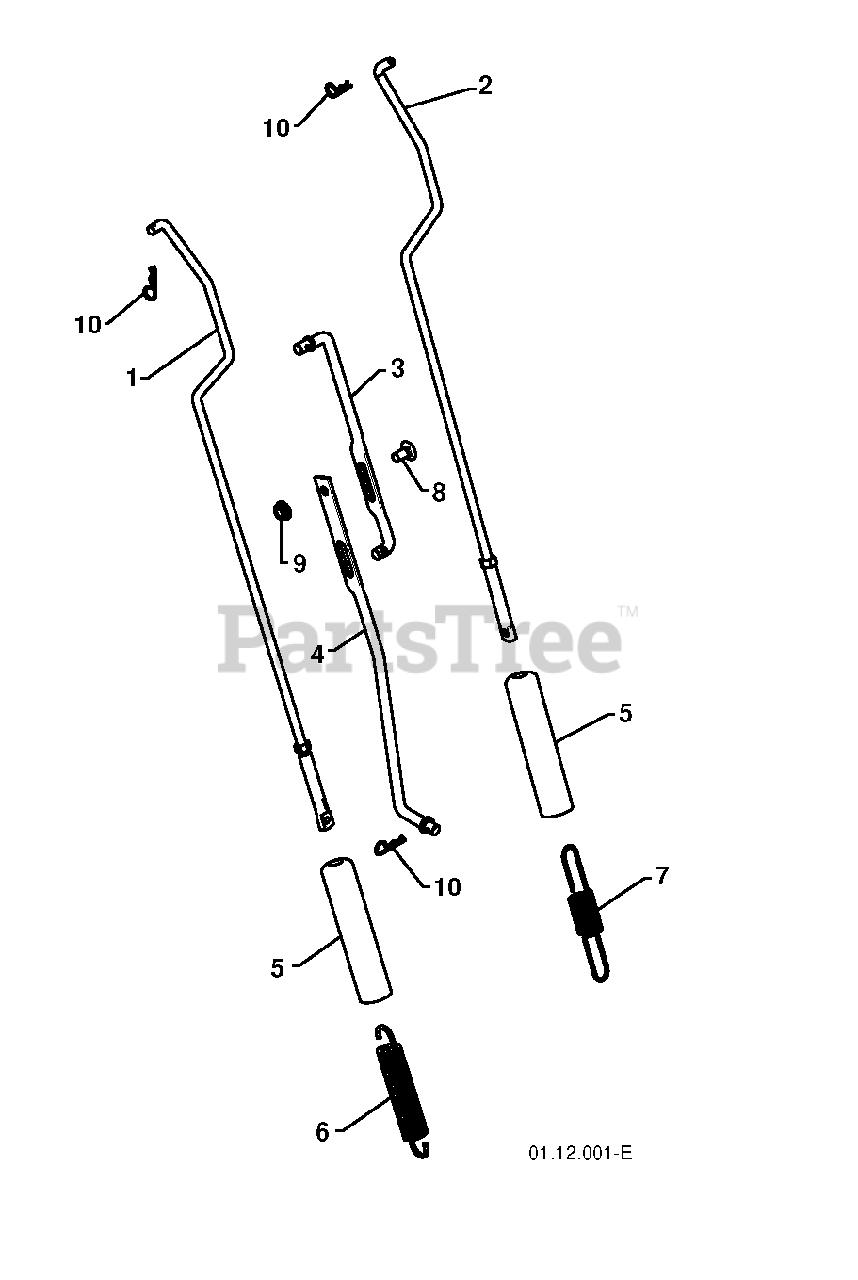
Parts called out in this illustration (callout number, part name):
1	ROD.IMPELLER.CONTROL.SNOW
2	ROD.TRACTION.CONTROL.SNOW
3	ROD, UPPER SPEED CONTROL
4	ROD, LOWER SPEED CONTROL.SNOW
5	SLEEVE, SPRING
6	SPRING.CONTROL.ROD.SNOW
7	SPRING.TRACTION.ROD.SNOW
8	BOLT
9	NUT.FLANGE.5/16
10	SPRING RETAINER
